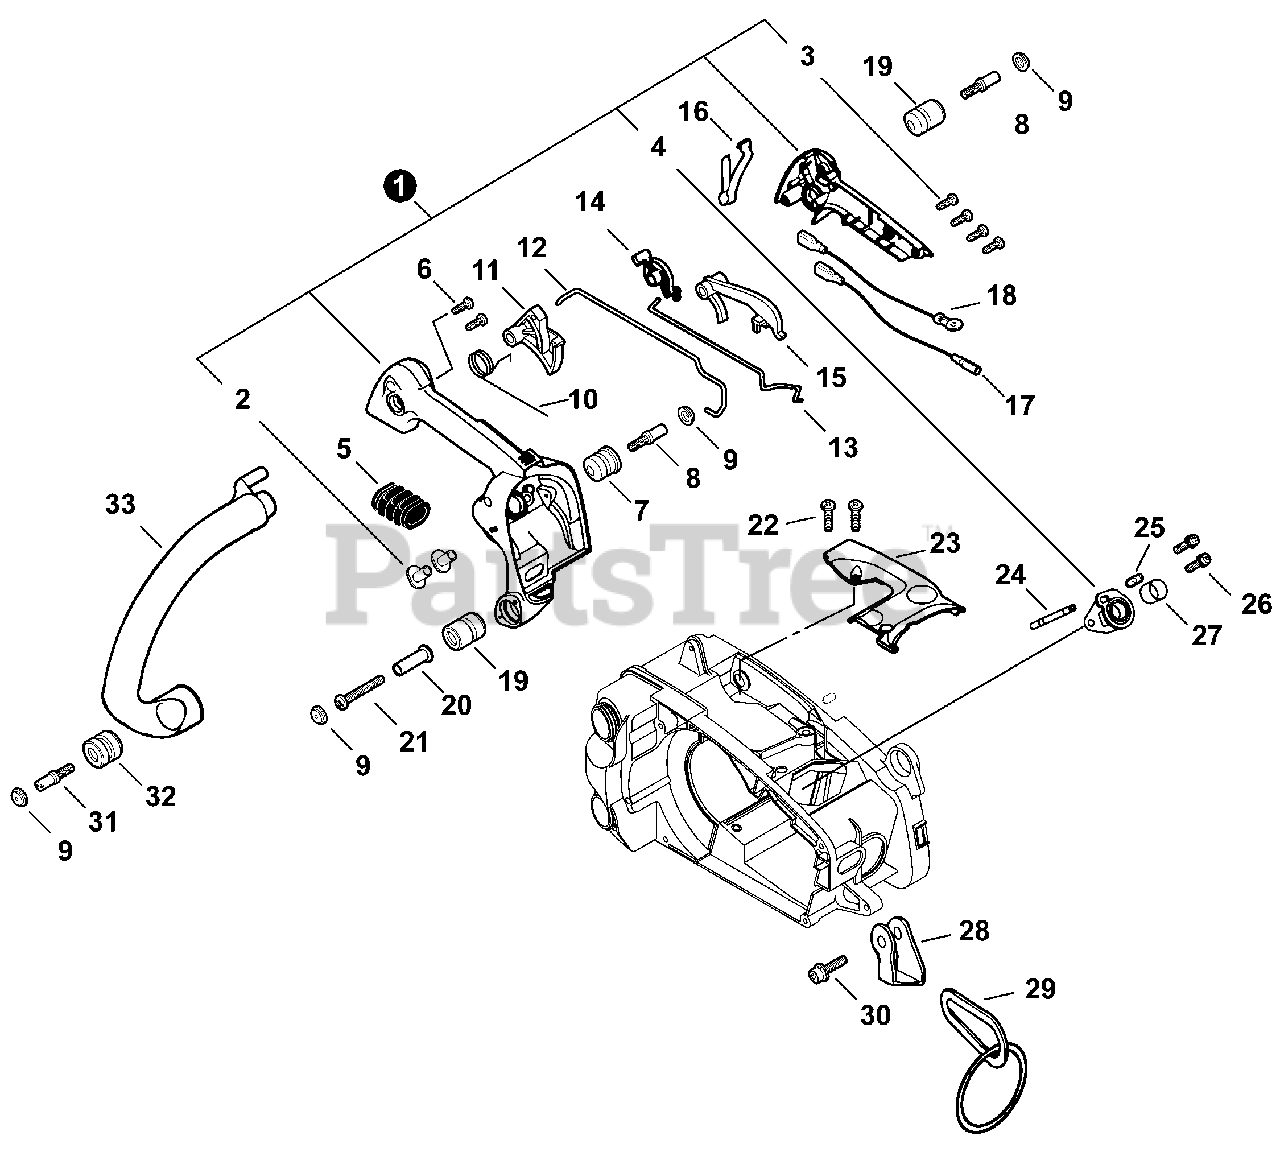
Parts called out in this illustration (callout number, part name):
1	HANDLE KIT, REAR
3	SCREW 4×16
4	BELLOWS, INTAKE
5	BELLOWS, INTAKE
6	SCREW 5×20
7	CUSHION 4
8	BOLT 4×15
9	CAP, CUSHION
10	SPRING, TORSION
11	TRIGGER, THROTTLE
12	ROD, THROTTLE
13	ROD, CHOKE
14	LEVER, CONTROL
15	LOCKOUT, THROTTLE
16	TERMINAL, LEAD
17	LEAD - GROUND
18	LEAD - IGNITION
19	CUSHION
20	COLLAR 4
21	SCREW, TAPPING 4×35
22	SCREW 4×12
23	COVER, DUST - ORANGE
24	PIPE, PULSE 3×7×65
25	COLLAR 3.2×6.5
26	SCREW 5×12
27	COLLAR 16
28	BRACKET, HARNESS
29	RING, HARNESS
30	BOLT 4×25
32	CUSHION 5
33	HANDLE, FRONT
